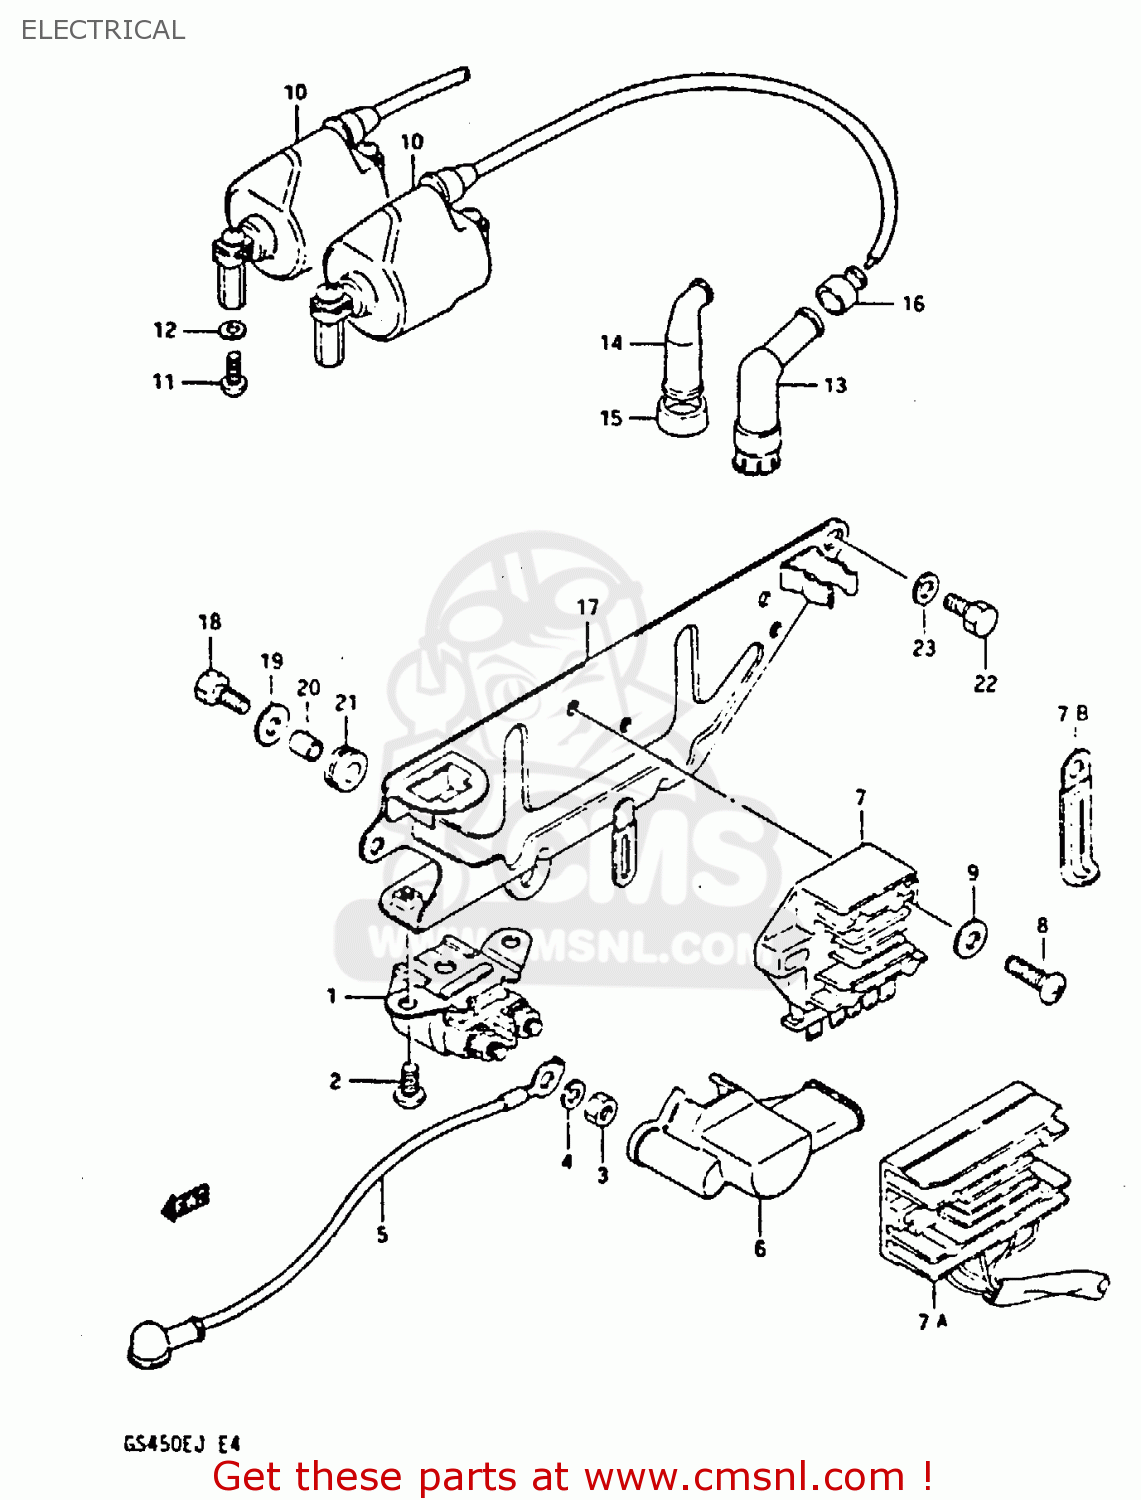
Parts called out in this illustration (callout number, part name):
1	RELAY ASSY,STARTING MOTOR
2	SCREW
3	NUT
4	WASHER,LOCK
5	WIRE,STARTER MOTOR LEAD
6	CAP,STARTER RELAY
7	RECTIFIER ASSEMBLY
7A	RECTIFIER ASSEMBLY
7B	CLAMP
8	SCREW
9	WASHER
10	COIL ASSEMBLY,IGNITION
11	SCREW
12	LOCK WASHER
13	CAP, SPARK PLUG (S)
14	CAP,SPARK PLUG
15	SEAL,SPARK PLUG
16	SEAL,SPARK PLU
17	PLATE, PARTS HOLDER
18	BOLT,M6X1X20
19	WASHER
20	SPACER
21	CUSHION
22	BOLT
23	WASHER,LOCK
